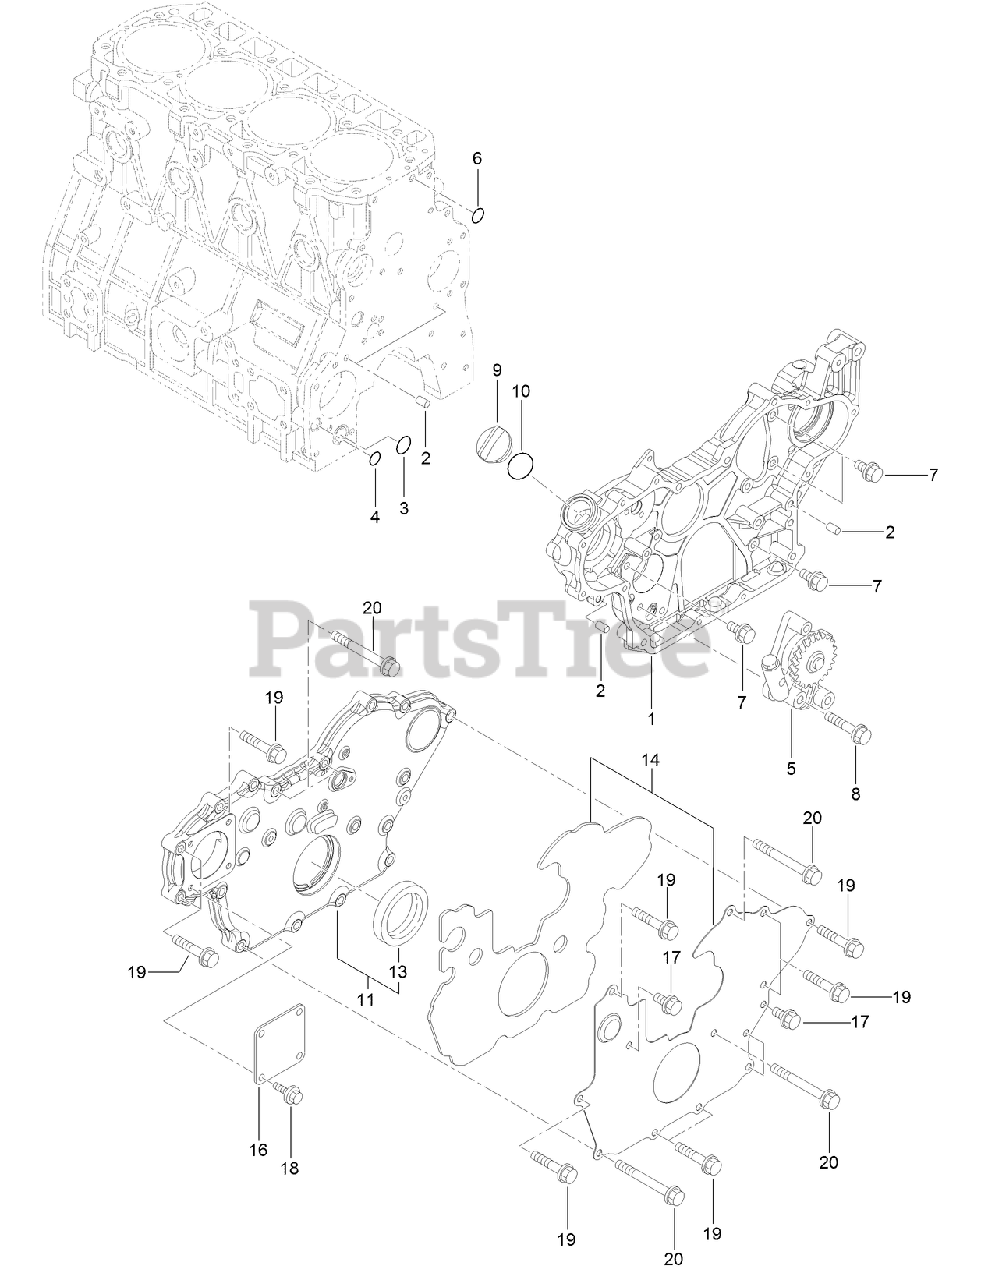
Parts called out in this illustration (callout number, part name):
1	CASE-GEAR
3	O-RING
4	O-RING
5	OIL PUMP ASM
6	O-RING
9	COVER-FILLER
10	O-RING
11	GEARCASE COVER ASM
13	SEAL-OIL
14	GEARCASE COVER ASM
